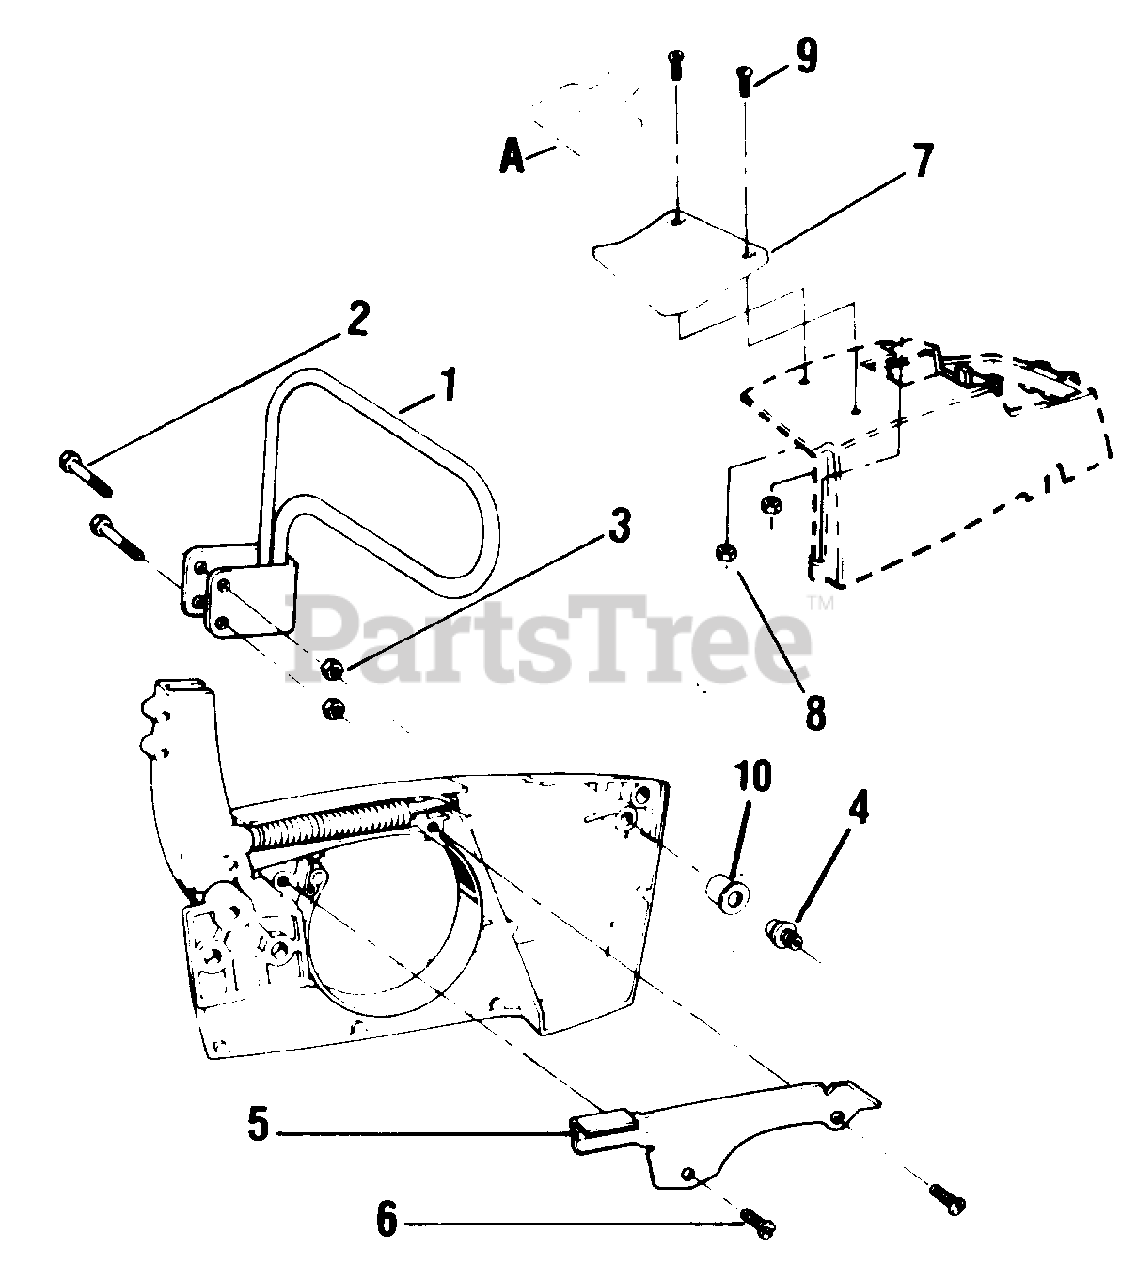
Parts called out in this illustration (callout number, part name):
1	Ass'y. - Handguard
2	Screw - 10 - 24 Hex Hd.
3	Locknut - 10 - 24
4	Bar Clamp Guide Stud
5	Bracket - Brake Band
6	Screw - 10 - 24 x 7/16 Taptite Hex Hd.
7	Shield - Heat
8	Nut - Heat Shield
9	Screw - Heat Shield 10 - 24 x 1/2 Pan Hd.
10	Bushing Guide
A	Decal - Instruction
